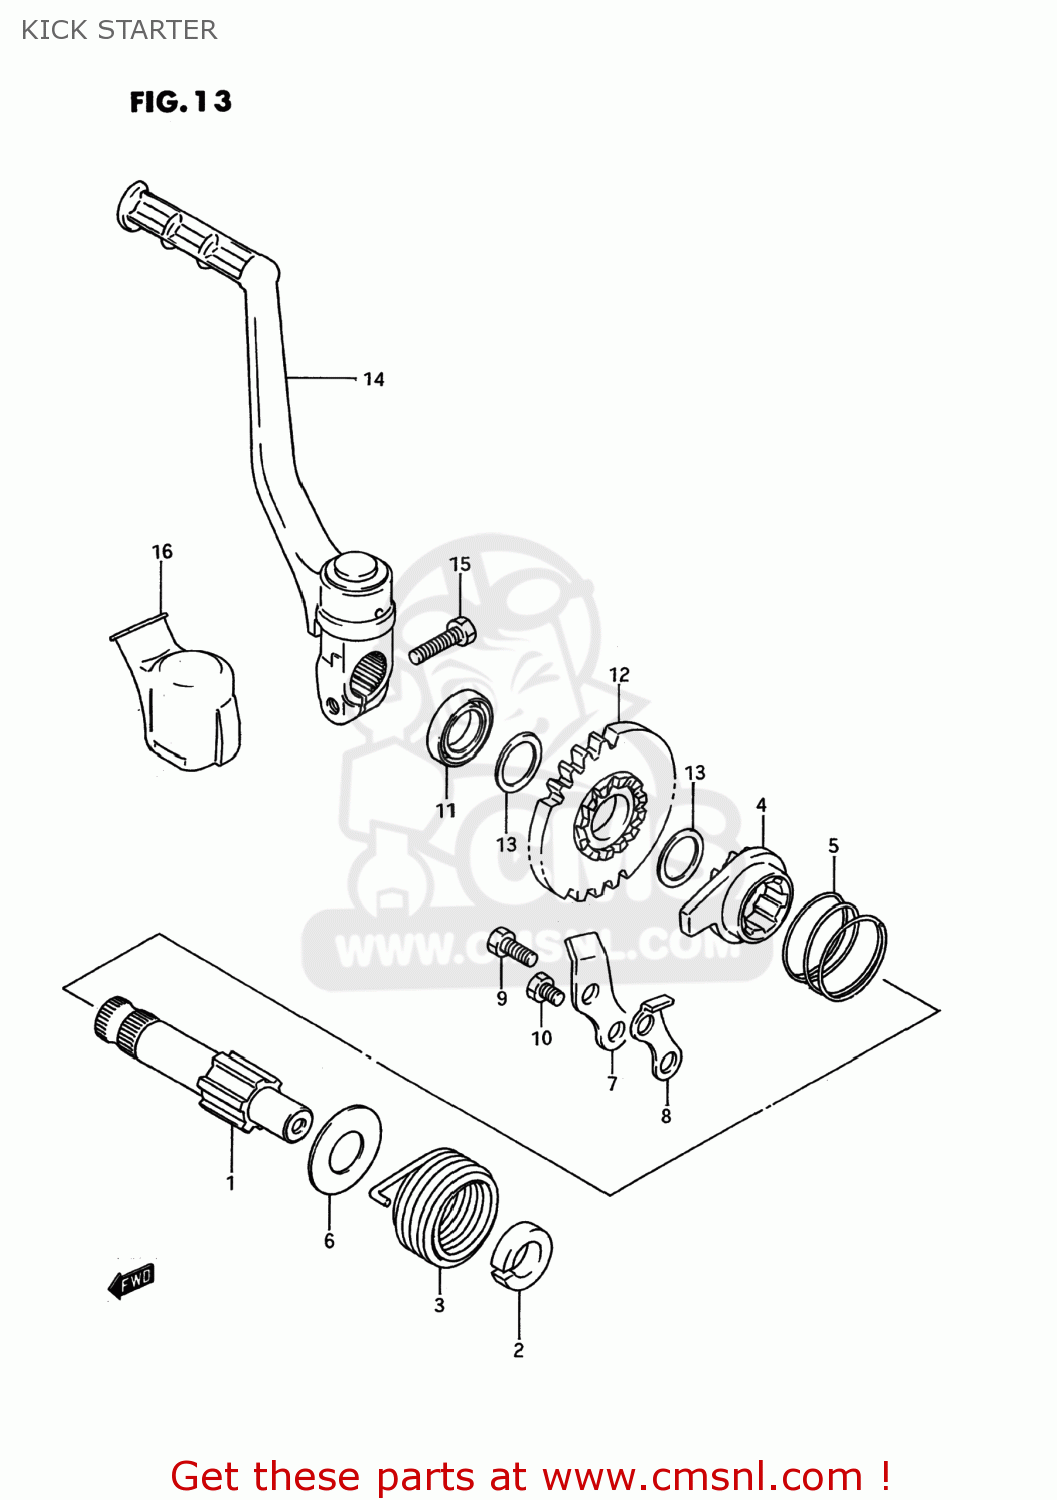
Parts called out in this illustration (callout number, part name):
1	SHAFT,KICK STARTER
2	GUIDE,SPRING
3	SPRING
4	STARTER,KICK
5	SPRING
6	WASHER
7	GUIDE,KICK STARTER
8	STOPPER,KICK STARTER
9	BOLT
10	BOLT 6X8
11	SEAL,OIL(14X24X6)
12	GEAR,KICK STARTER DRIVE
13	WASHER
14	LEVER ASSEMBLY,KICK STARTER
15	BOLT
16	COVER,KICK LEVER JOINT
